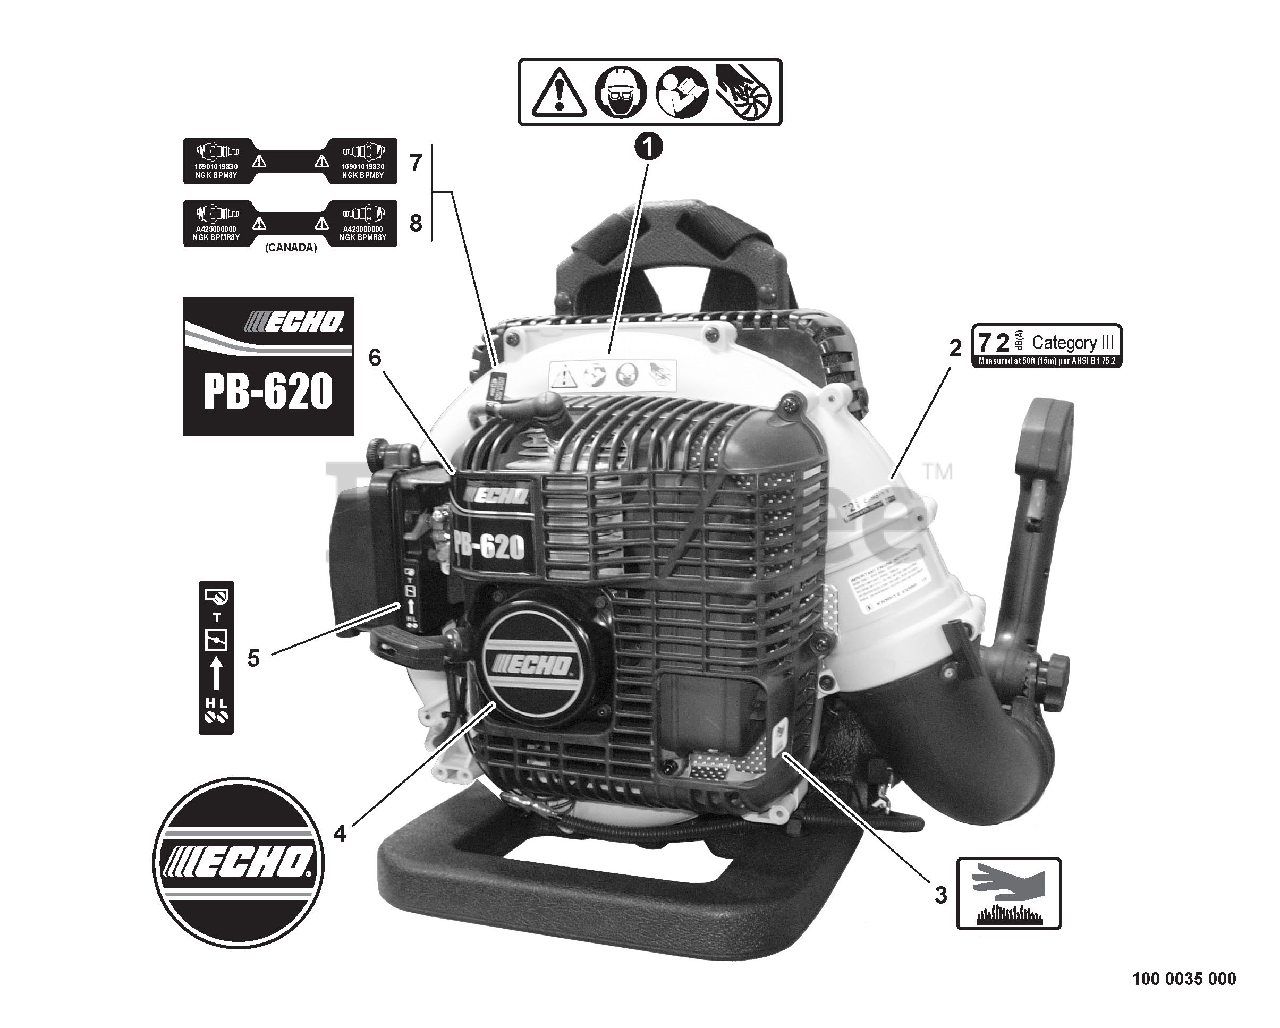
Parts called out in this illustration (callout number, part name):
1	LABEL - CAUTION
2	LABEL - NOISE 72dB(A) CAT III
3	LABEL - HOT SURFACE
4	LABEL - ECHO
5	LABEL - CHOKE
6	LABEL - MODEL PB-620
7	LABEL - SPARK PLUG -- BPM-8Y
8	LABEL - SPARK PLUG -- BPMR-8Y
